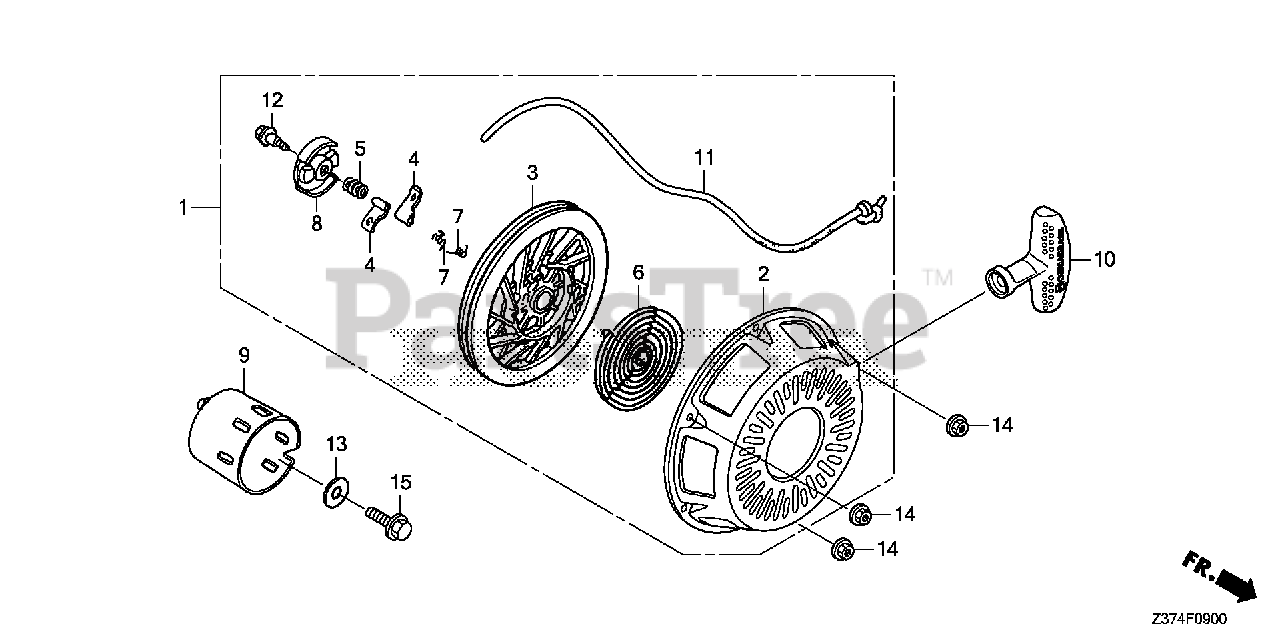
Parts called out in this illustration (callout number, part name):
1	STARTER ASSY., RECOIL
2	CASE, RECOIL STARTER
3	PULLEY, RECOIL STARTER
4	RATCHET, STARTER
5	SPRING, FRICTION
6	SPRING, STARTER RETURN
7	SPRING, RATCHET
8	RETAINER, SPRING
9	PULLEY, STARTER
10	GRIP, STARTER (COO)
10	GRIP, STARTER
11	ROPE KIT, RECOIL
11	ROPE, RECOIL STARTER
12	SCREW, CENTER
13	WASHER (10MM)
14	NUT, FLANGE (6MM)
15	BOLT, FLANGE (10X25)
